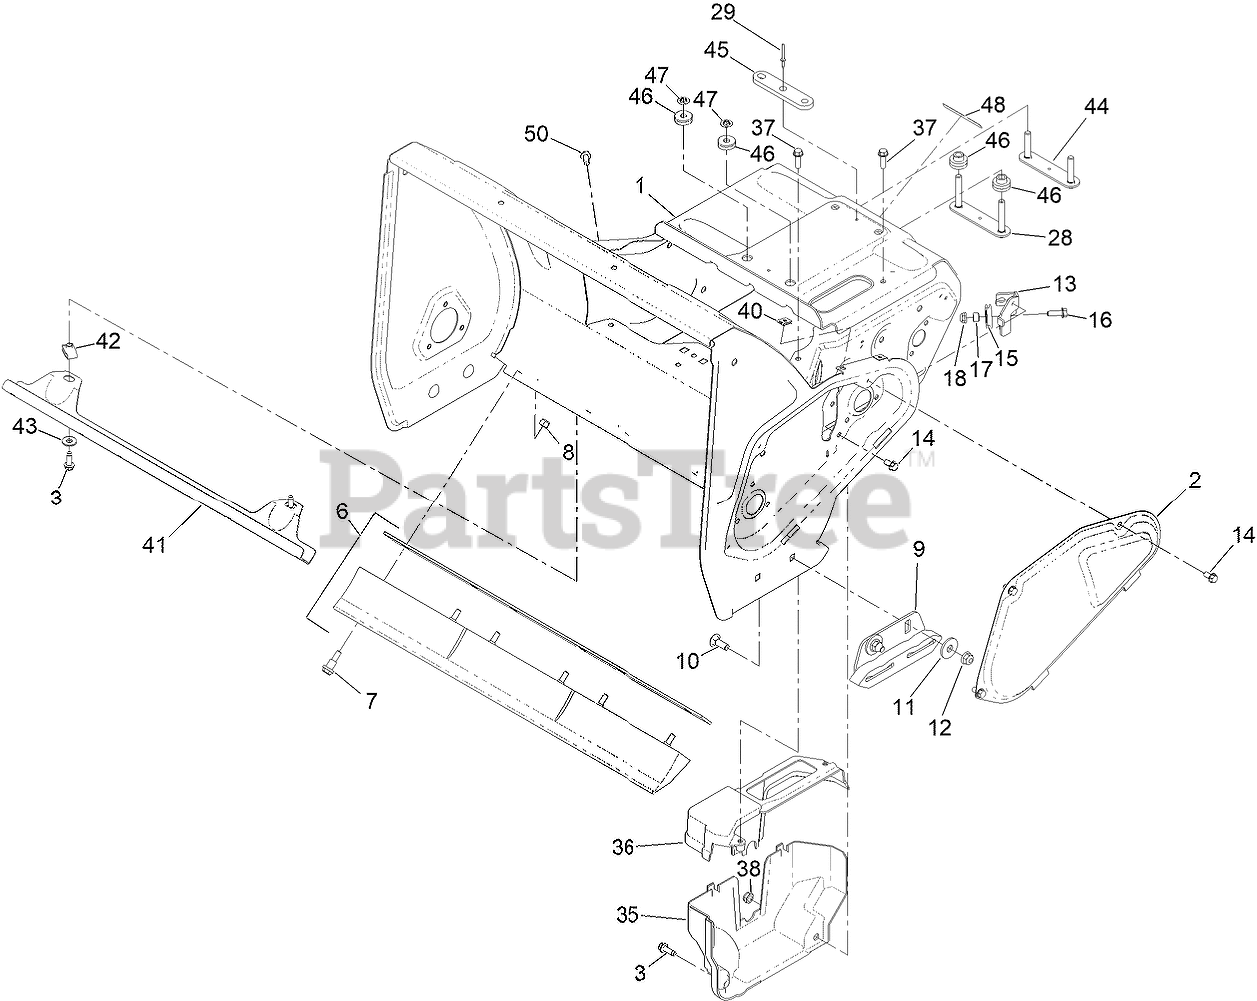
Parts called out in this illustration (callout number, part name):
2	COVER-BELT
3	SCREW-HWHTF
6	SCRAPER ASM
7	BOLT-SHOULDER
8	NUT-LOCK, NI
9	SKID ASM
10	SCREW-CARR
11	WASHER
12	NUT-HF, NI
13	BRACKET-CABLE
14	SCREW-HWH
15	CABLE-PULLEY
16	SCREW-HHF
17	SPACER-BLADE, ROTOR
18	NUT-HF
28	PLATE-STUD, FRONT
29	RIVET
35	COVER-BELT, LOWER
36	COVER-BELT, UPPER
37	SCREW-HWH
38	NUT-LOCK, NI
40	NUT-SPEED
41	SUPPORT-FRAME, LOWER
43	WASHER-FLAT
44	PLATE-STUD, REAR
45	PLATE-SPACER
46	ISOLATOR-ENGINE
47	RING-RETAINING, BOLT
48	DECAL-WARNING
50	SCREW-HWH
